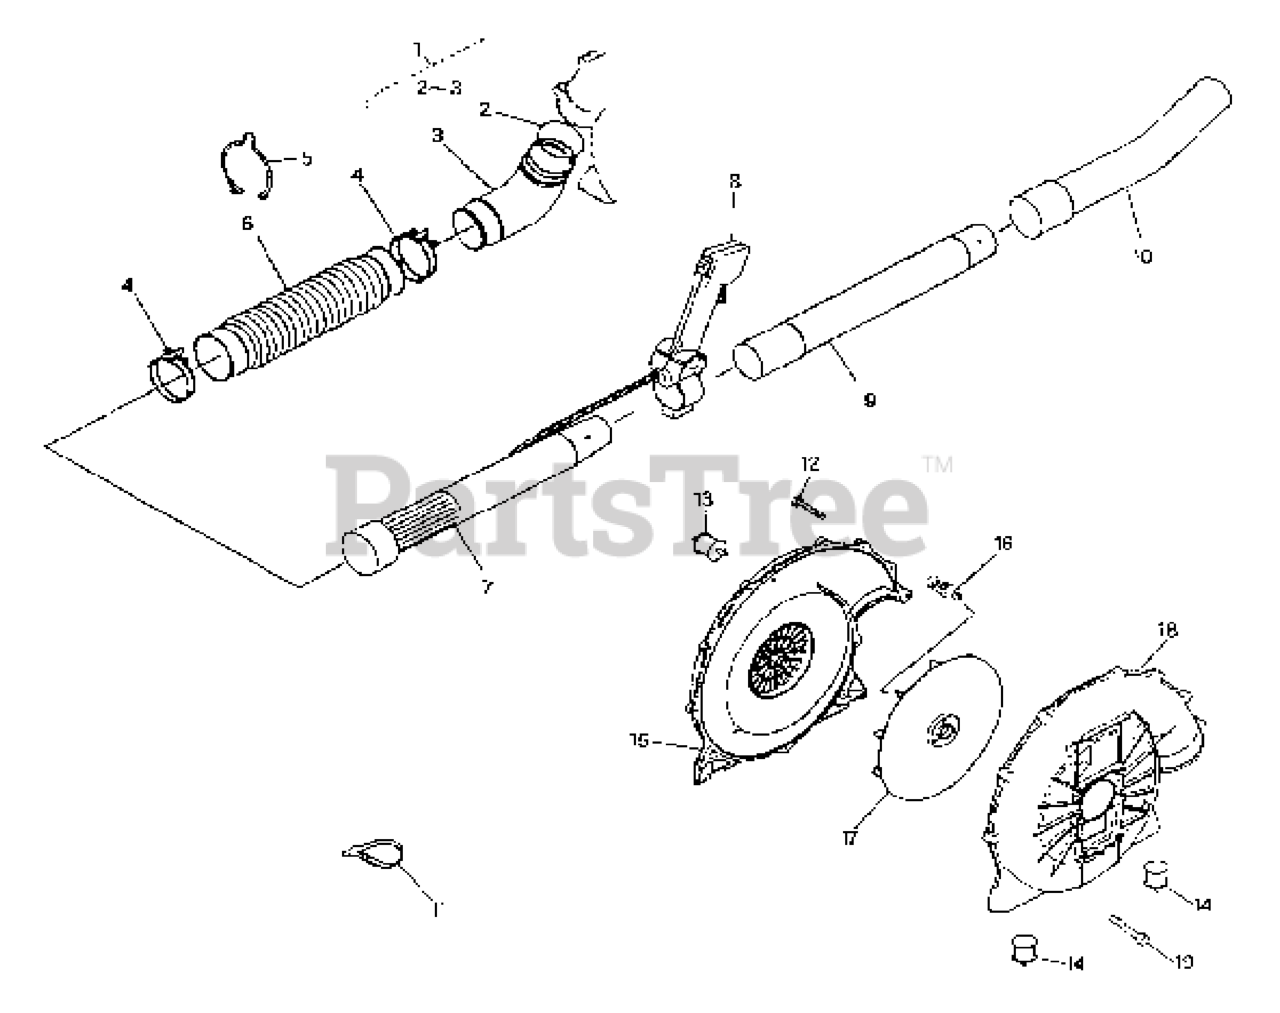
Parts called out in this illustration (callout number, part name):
1	ELBOW PIPE C.P.
2	O'RING
3	ELBOW PIPE
4	HOSE BAND
5	CLAMP
6	FLEX. PIPE 36084-101
7	BASE PIPE
8	THROTTLE ASSEMBLY
9	MIDDLE PIPE
10	BEND PIPE
11	BAND FR66820XX006
12	SCREW
13	ANTIVIBE MOUNT
14	ANTIVIBE MOUNT
16	BOLT
19	BOLT
